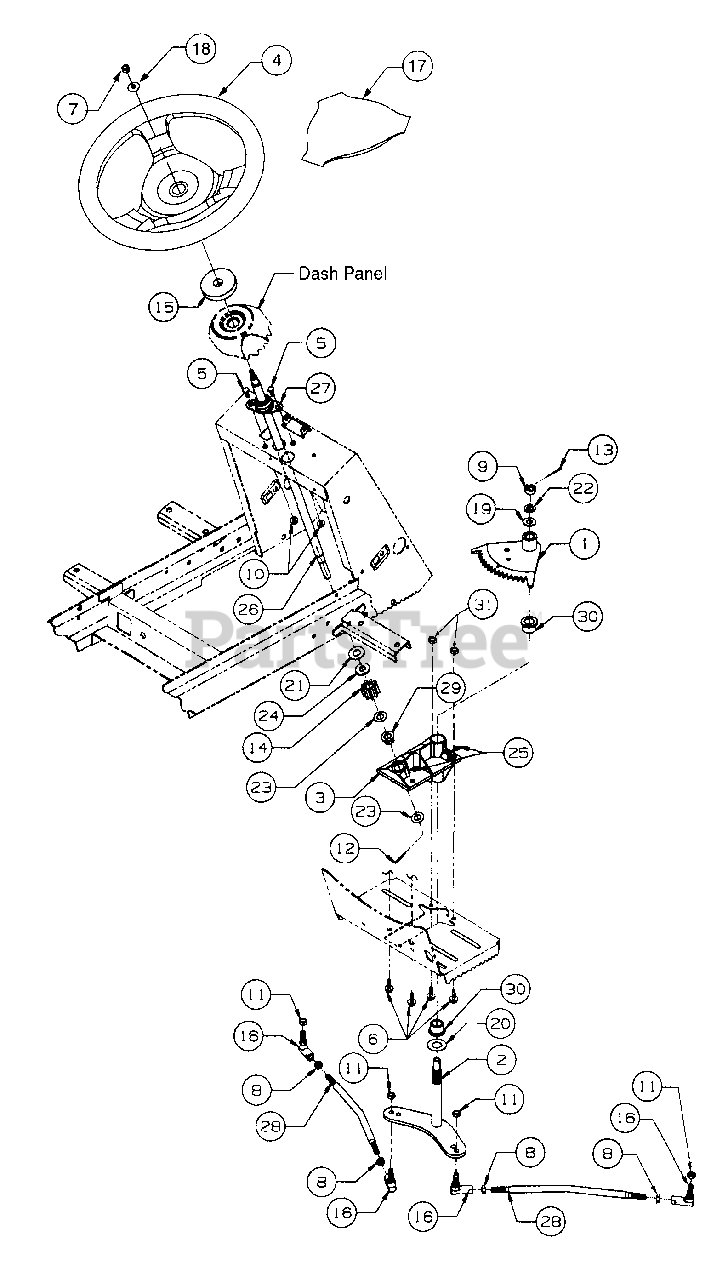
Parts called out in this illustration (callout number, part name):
1	Segment Assy, 18T Steering
2	Arm Assy, Lower Steering
3	Housing Assy,
4	Steering Wheel, Soft Grip
5	Screw, Hex Cap, 1/4 - 20 x .62, GR5
6	Screw, Hex Hd Cap, 5/16-18 x 1 GR5
7	Nut, Hex Center Lock, 5/16-18
8	Nut, Jam, 3/8-24 GR2
9	Nut, Hex Slotted, 1/2-20 GR5
10	Nut, Hex Flange Lock, 1/4-20
11	Nut, Hex Lock, 3/8-24 GR5
12	Pin, Cotter, 1/8 Dia x 1
13	Pin, Cotter, 3/32 Dia x 1.25
14	Pinion, Steering
15	Gasket, Steering
16	Joint, Ball, 3/8-24
17	Insert, Steering Wheel
18	Washer, Bell, .340 x .88 x .06 Thk
19	Washer, Flat, .510 x 1 x .06 Thk
20	Washer, Flat, .760 x 1.5 x .03 Thk
21	Washer, Flat, .56 x 1 x .04 Thk
22	Washer, Lock, 1/2
23	Washer, Flat, .531 x 1 x .027 Thk
24	Wshr, Rubber Flat, .50 x 1.12 x .125 Thk
25	Fitting, Grease, 3/16 Drive Type
26	Shaft, Steering
27	Bearing, Flange
29	Bearing, Flange, .503 ID
30	Bearing, Bronze Flange, .75 ID
31	Nut, Hex Center Lock, 5/16-18
